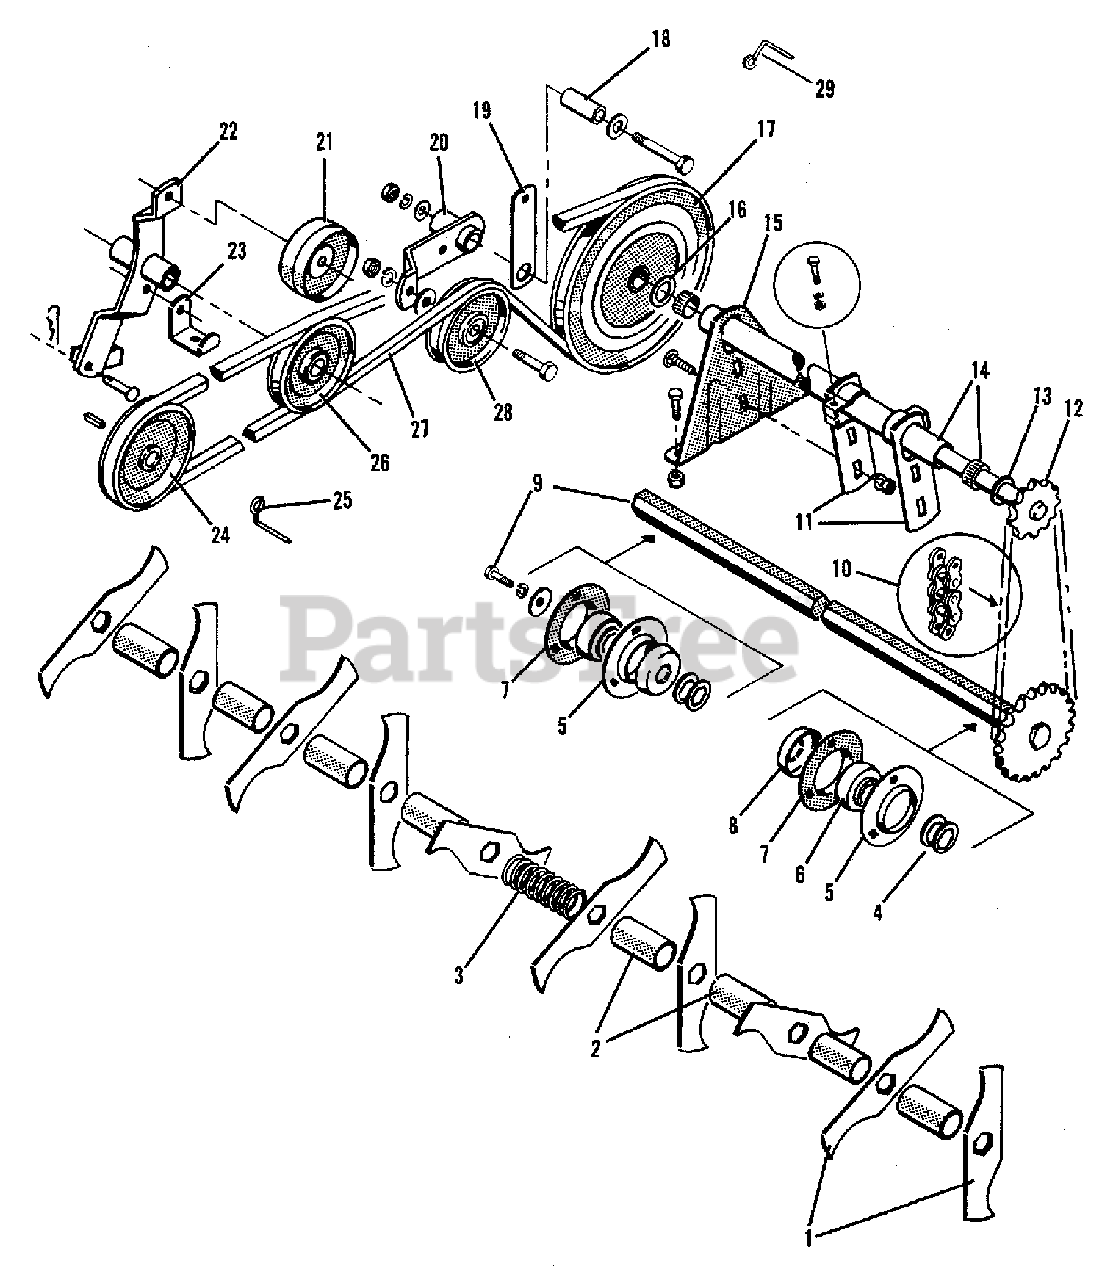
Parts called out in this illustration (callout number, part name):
1	TINE, Lawn Revitalizer
2	SPACER, Tine
3	SPRING, Tine Compression
4	WASHER, Special Hex.
5	FLANGE, Bearing
6	BEARING ASSEMBLY, Nylon
7	FLANGE, Bearing (w/Lube Fitting)
7	SCREW, 5/16NC x 1/2, Self-Tap
8	GUARD, Bearing Dust
9	SHAFT ASSEMBLY, Tine (w/Sprocket)
9	LOCKWASHER, 5/16
9	CAPSCREW, 5/16NC x 1/2
10	CHAIN ASSEMBLY, Drive
11	SUPPORT ASSEMBLY, Clamping
11	BOLT, 7/16NC x 1
11	LOCKWASHER, 7/16
11	NUT, 7/16NC
11	CAPSCREW, 5/16NC x 1-1/2
11	LOCKWASHER, 5/16
11	NUT, 5/16NC
12	SHAFT ASSEMBLY, Drive (w/Sprocket)
14	HOUSING ASSEMBLY, Shaft (Includes BEARINGS)
14	FITTING, Lube
15	SUPPORT, Drive Shaft
15	CAPSCREW, 5/16NC x 5/8
15	LOCKWASHER, 5/16
15	NUT, 5/16NC
15	NUT, 5/15NC, Lock
17	PULLEY, Drive Shaft
17	KEY, #9 Woodruff
18	CAPSCREW, 7/16 NC x 3-1/2
18	WASHER, 3/8, Plain
18	WASHER, 7/16, Plain
18	LOCKWASHER, 7/16
18	NUT, 7/16NC
19	SUPPORT, Rear Belt Guard
19	BOLT, 5/16NC x 2/4
19	NUT, 5/16NC, Wing
20	LEVER ASSEMBLY, Clutch
21	PULLEY, Idler
21	CAPSCREW, 3/8NC x 1-1/4
21	WASHER, 5/16, Plain
21	LOCKWASHER, 3/8
21	NUT, 3/8NC
22	ARM ASSEMBLY, Idler
22	PIN, Round Head Hitch
22	PIN, Quick
23	BRACKET, Belt Guard
23	CAPSCREW, 3/8NC x 7/8
23	WASHER, 5/16, Plain
23	LOCKWASHER, 3/8
23	NUT, 3/8NC
24	PULLEY, Transmission
24	KEY, #9 Woodruff
25	STOP, Belt
26	PULLEY, Idler
28	CAPSCREW, 3/8NC x 1-1/4
28	WASHER, 5/16, Plain
28	LOCKWASHER, 3/8
28	NUT, 3/8NC
29	STOP, Belt
